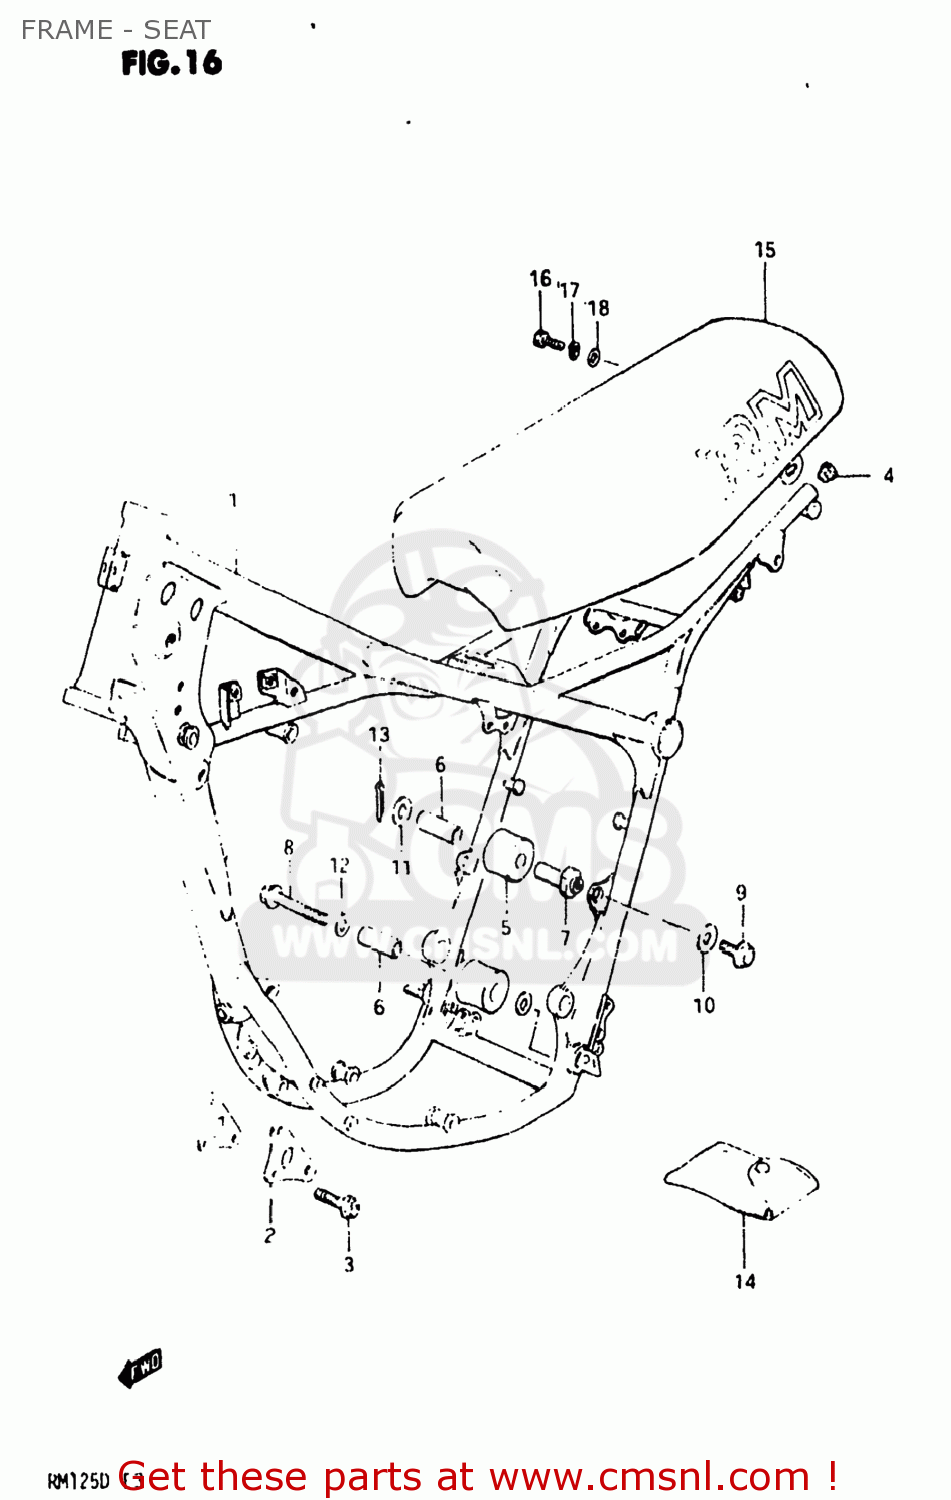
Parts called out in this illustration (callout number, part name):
1	FRAME
2	PLATE,ENG MTG
3	BOLT(8X36)
4	PLUG(OD:17)
5	ROLLER,CHAIN LENGTH CONTROL
6	SPACER,CHAIN LENGTH ROLLER
7	BOSS,CHAIN LENGTH ROLL
8	BOLT(8X45)
9	BOLT
10	WASHER
11	WASHER
12	WASHER
13	PIN 25X20
14	TOOL SET
15	SEAT ASSEMBLY
16	BOLT
17	LOCK WASHER
18	WASHER
